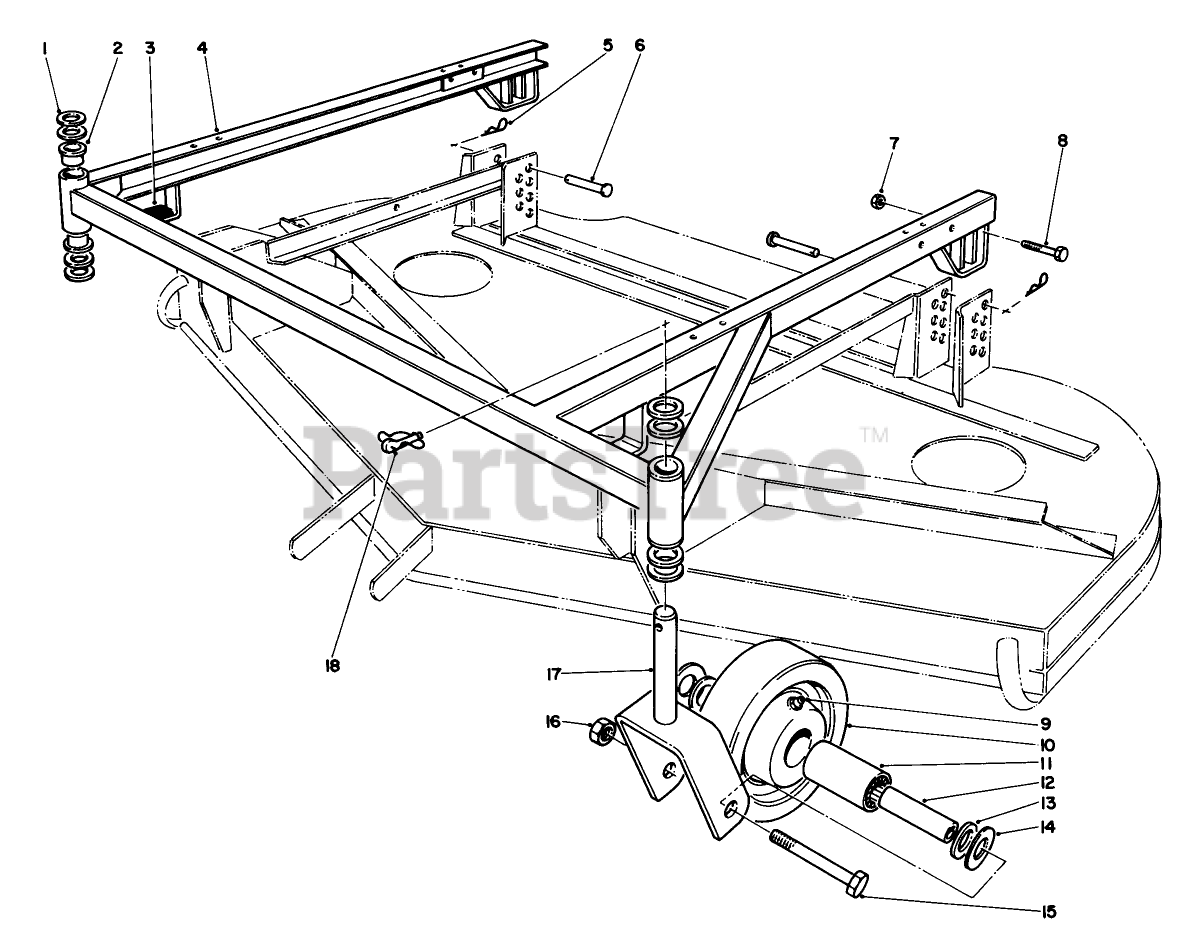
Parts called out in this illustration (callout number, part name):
1	WASHER-THRUST
5	PIN-HAIR
6	PIN-CLEVIS
7	NUT-LOCK, CONE
8	SCREW-HH
9	FITTING-GREASE
10	WHEEL
11	ROLLER BEARING
12	SPANNER BUSHING
13	BEARING RETAINER
14	THRUST WASHER
15	SCREW-HH
16	NUT-HEX
18	PIN-LYNCH
